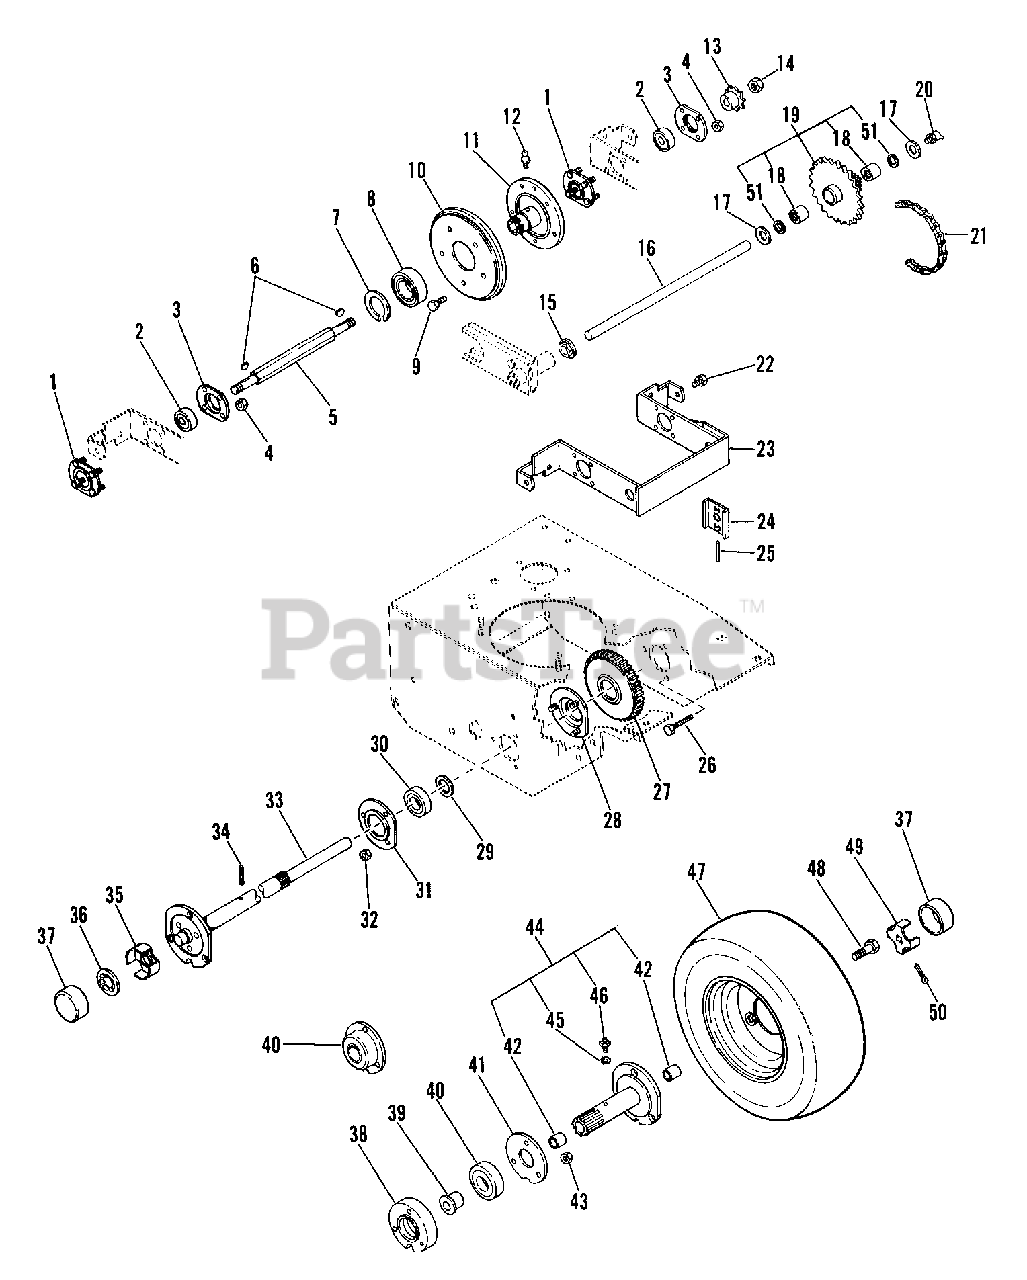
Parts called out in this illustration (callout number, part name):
1	BEARING FLANGE
2	BRG-BALL .500X1.375X.437
3	BEARING FLANGE
4	NUT-LK DUAL FACE 10-24 PL
5	HEX SHAFT
6	KEY-WDRF .125X.625X.250 SAE5
7	RG-RTNG-EXT 1.250X.050
8	BRG-BALL 1.25X2.18X.63
9	BLT-SERHFWH .31-18X.50 PL
10	FRICTION DISC
12	SPIN DRIVE ZERK FITTING
13	9 TOOTH SPROCKET
14	NUT-LK-CTR .50-20 PL
15	FLANGE BUSHING
16	CARRIER SHAFT
17	WSHR-FL-STL .630X1.005X.062 PL
18	BRG-NEEDLE .625X.812X.50
19	PINION AND SPROCKET ASSEMBLY
20	HYDRAULIC DRIVE FITTING
21	CHAIN
22	SCR-TAP .312-18X.50 HWH PL TR
23	CARRIER
24	LOCATING PLATE
25	PIN-ROLL .188X1.50
26	BLT-HEX .25-20X1.25 PL GR5
26	BLT-HEX .25-20X.63 PL GR2
27	DIFFERENTIAL ASSEMBLY
28	BEARING FLANGE
29	WSHR-FL-STL .880X1.380X.062
30	BRG-BALL .876 X 1.750 X .50
31	BEARING FLANGE
32	NUT-LK-FLG .250-20 PL
33	R.H. AXLE SHAFT
34	PIN-ROLL .188X1.25
35	SPINDLE CUP
36	PUSHNUT
37	HUB CAP
38	BEARING FLANGE
39	BSHG-FLG 1.125X1.25X.75X1.38
40	BRG-BALL 1.25X2.18X.63
40	BEARING ASSEMBLY
41	COVER
42	BSHG-SLV .690X.814X.625
43	NUT-LK-CTR .250-20 PL
44	L H AXLE ASSEMBLY
45	WSHR-LK .250X.047 LT PL
46	SPIN DRIVE ZERK FITTING
47	TIRE 13X5.00-6
47	TIRE
47	WHL 13X5.00-6
48	SCR-TAP .500-20X.62 HH PL
49	SPINDLE CUP
50	PIN-COTR .12X1.0 PL
51	SEAL .625X.875X.125
